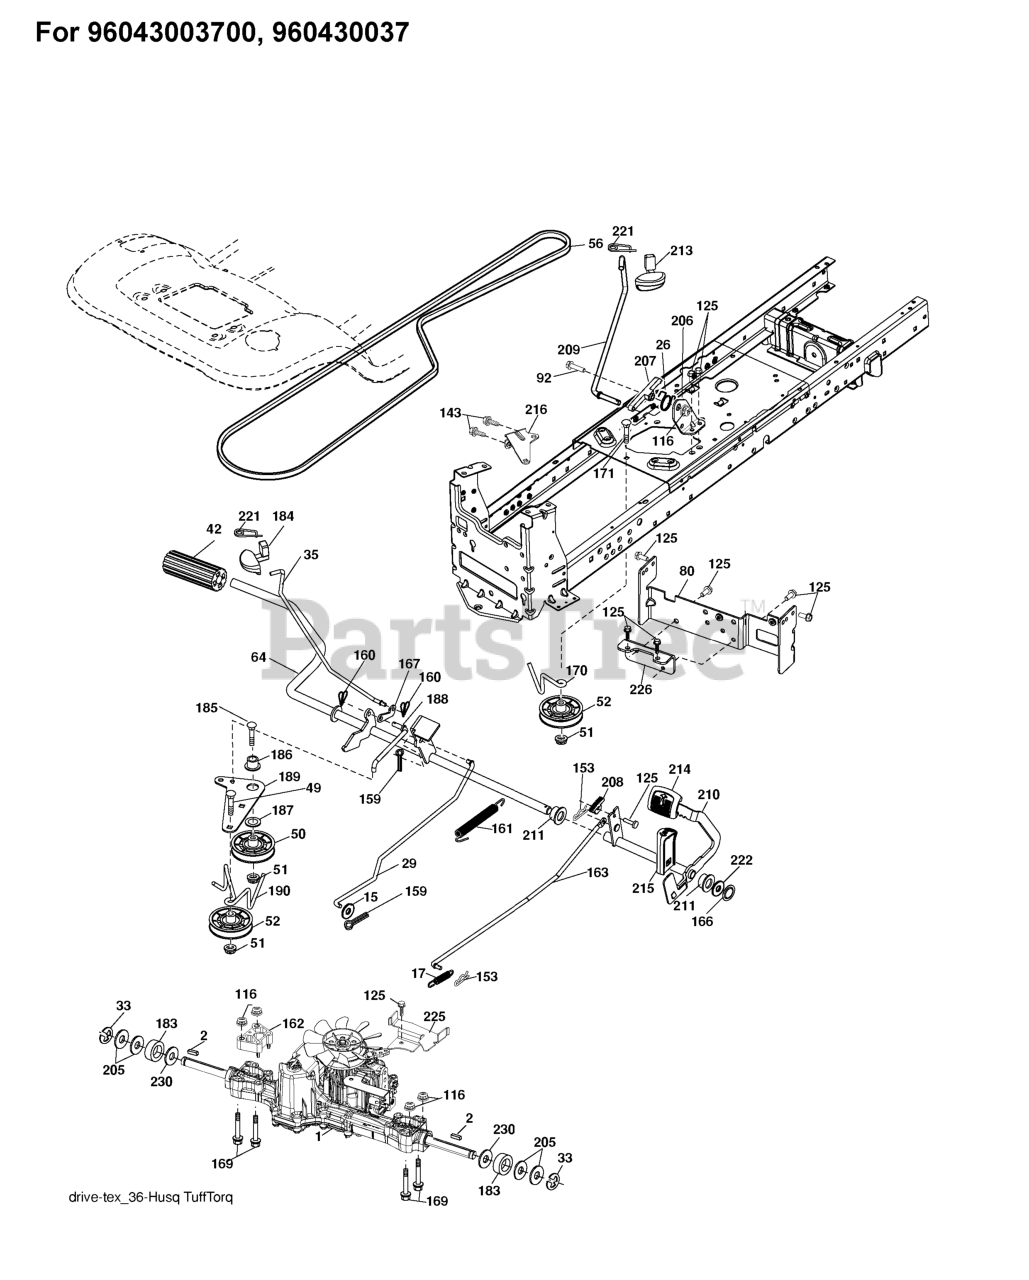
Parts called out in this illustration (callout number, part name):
1	TRANSAXLE, TUFFTORQ K46
2	SQUARE KEY
15	WASHER
17	SPRING.BRAKE.K46
26	SPRING.RETURN.CRUISE
29	ROD.BRAKE.K46
35	ROD.BRAKE.PARKING.GT.H
42	PEDAL COVER T
50	IDLER.FLAT.910.OFFSET
51	NUT LOCK FLG 3/8-16 UNC
52	IDLER.V-GROOVE.910.OFFSET
56	V-BELT.MOWER.92.40.42/K46
64	SHAFT.ASM.PEDAL.BRK.CNTR
80	STRAP TORQUE
92	BOLT
116	NUT LOCK HEX FLANGE 5/16-18
125	SCREW
143	Screw 5/16-18 x 1/2 Hex, Self Tapping 5/16-18 x 1/2
153	RETAINER M
159	COTTER PIN
160	RETAINER CLIP
161	SPRING.RETURN.CLUTCH.2006
162	SPACER.TRANSAXLE.18&22
163	ROD.CONTROL.PEDAL.K46
166	NUT.PUSH.625.2006
167	LATCH.BRAKE.SPRING
169	BOLT.HEX.FLNG.5/16-18X3.75
170	KEEPER.V-IDLER.CENTER.
171	BOLT
183	SPACER AXLE
184	HANDLE.PARKG.BRK.HUSQ X667
185	BOLT
186	SPACER.RETAINER
187	WASHER 12/32X2X10GA
188	RP.LINK.CLUTCH.GROUND.DRIVE
189	BELLCRANK.GROUND.DRIVE.TEX.
190	KEEPER.BELLCRANK.DRIVE
206	BRKT.MOUNT.LATCH.CRUIS
207	LATCH.CONTROL.CRUISE
208	GEAR.SECTOR.CONTROL.CR
209	ROD.CONTROL.CRUISE.GT.
210	ROCKER.ASM.PEDAL.CONTR
211	BEARING.NYLON
213	KNOB.CONTROL.CRUSIE.HU
214	PEDAL.FORWARD.TEX.GT.4
215	PEDAL.REVERSE.TEX.GT.4
216	BRACKET.PULLEY.IDLER.W/TEX
221	RETAINER.SPRING.CLIP.H
222	WASHER 21/32 X 1-1/4 X 10 GA.
225	KEEPER.BELT.TRANSAXLE.K46
226	BRACKET.MOUNT.TORQUE.K46.TLT
230	WASHER.HARDENED
